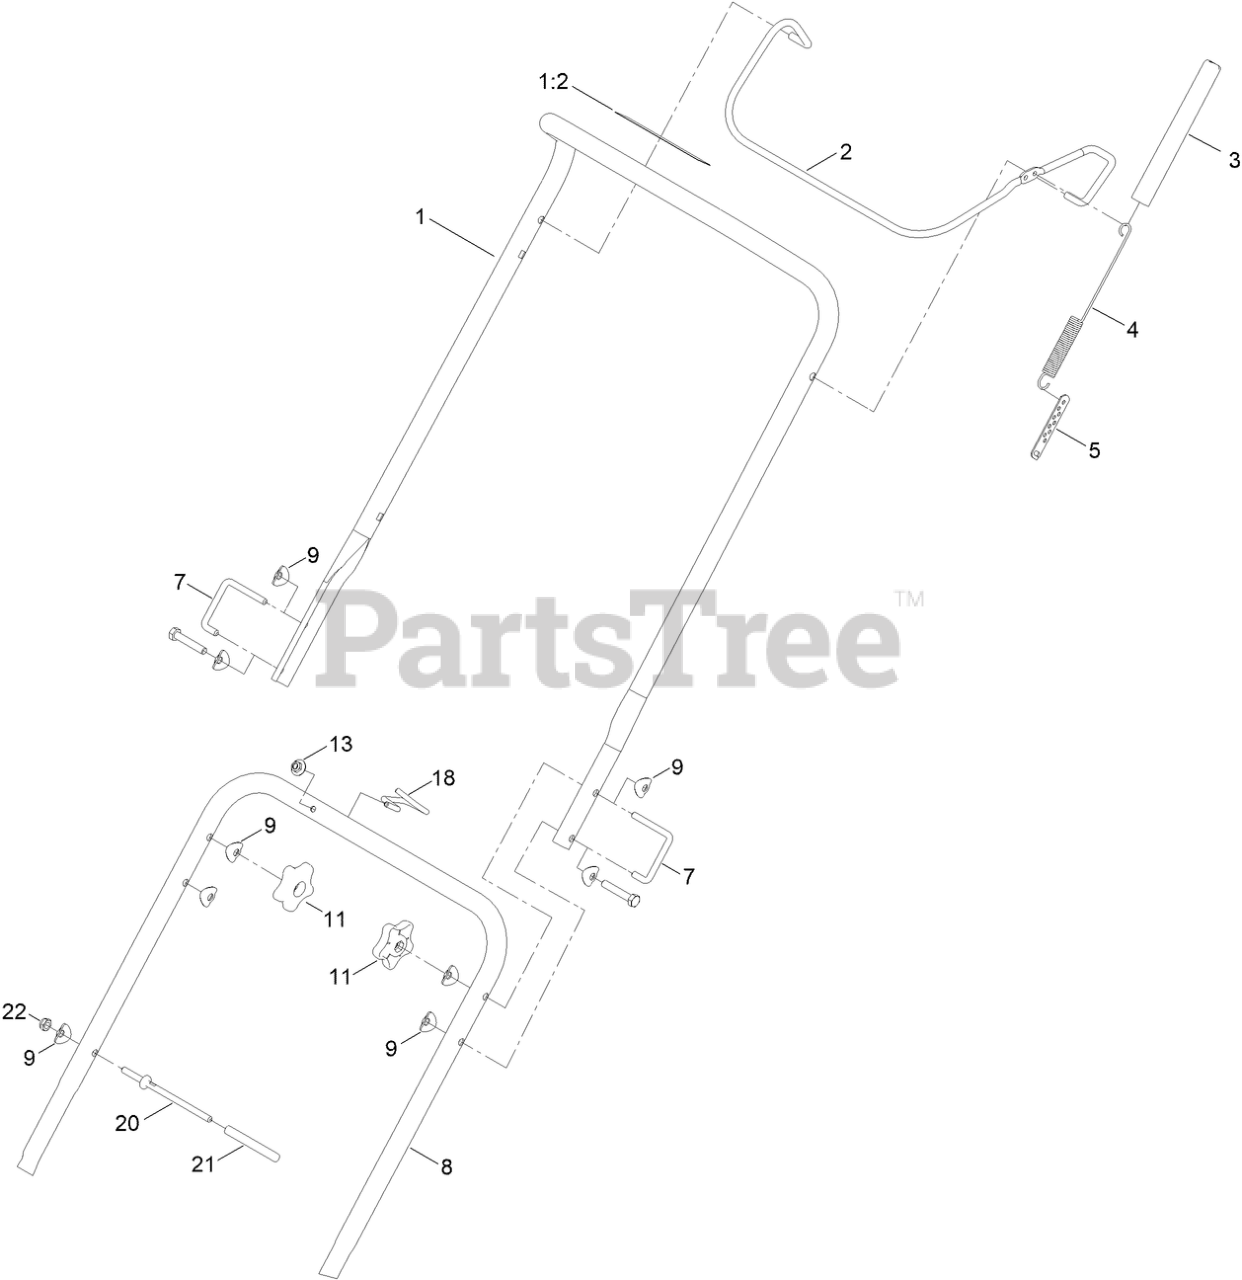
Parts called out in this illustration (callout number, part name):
1	UPPER HANDLE ASM (W/ DECAL)
1:2	DECAL-DRIVE, ROTOR
2	BAIL-CONTROL
3	COVER-SPRING
4	SPRING-EXTENSION, CLUTCH
5	ADJUSTER-CLUTCH CABLE
7	LOCK-HANDLE
8	HANDLE-LOWER
9	WASHER
11	KNOB-HANDLE
13	NUT-HF
18	GUIDE-ROPE
20	SUPPORT-SWITCH BOX
21	CAP-SUPPORT
22	NUT-LOCK, NI
